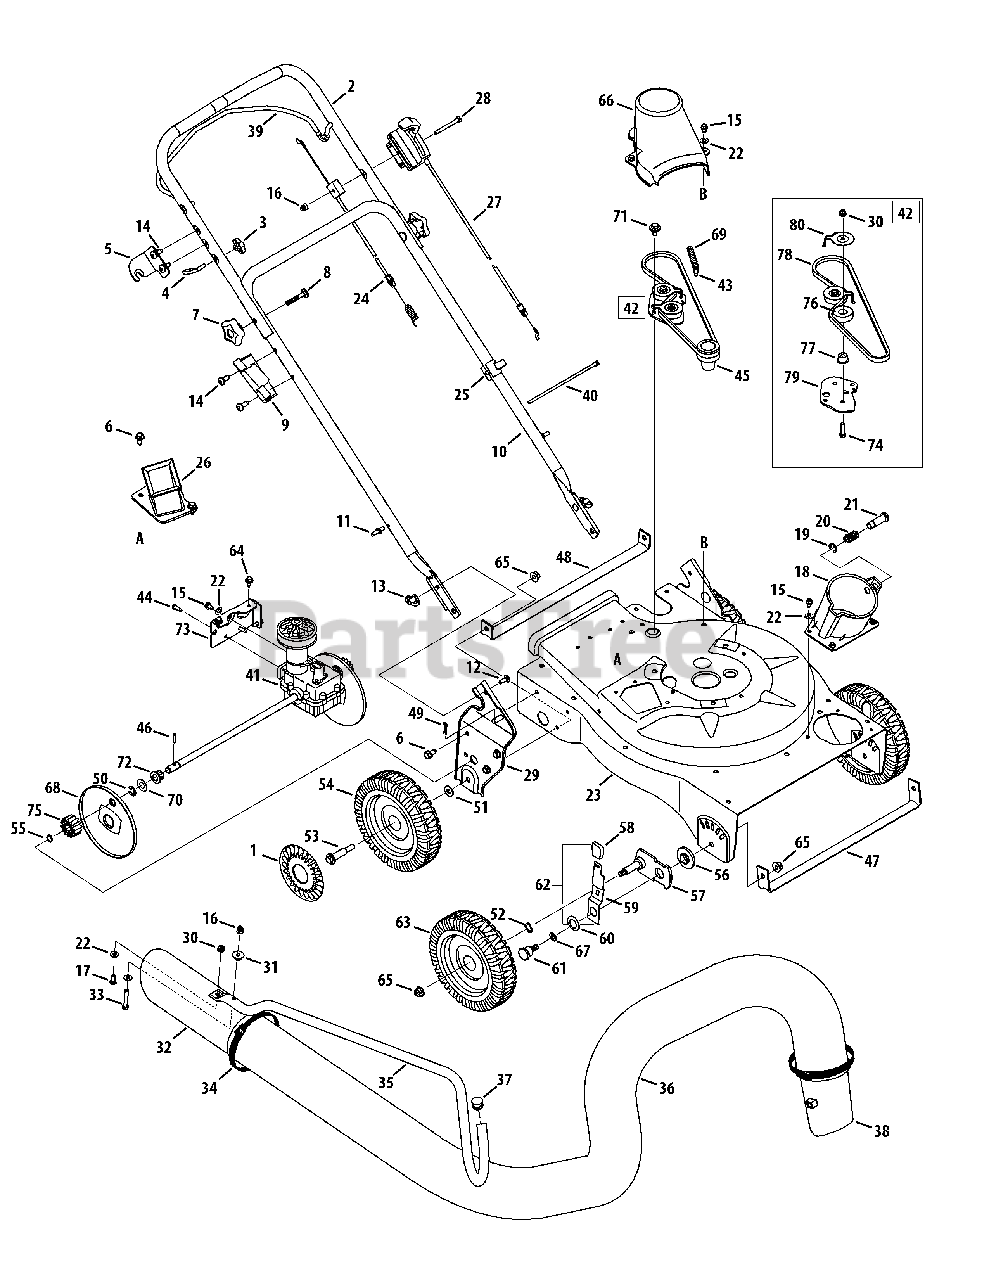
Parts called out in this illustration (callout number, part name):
1	Hub Cap
2	Upper Handle
4	Eye Bolt
5	Upper Handle Bracket
6	Hex Cap Screw 5/16-12 x.750
7	Handle Knob 5/16-18
8	Carriage Bolt
9	Nozzle Handle Clip
10	Lower Handle
11	Studs
12	Carriage Screw 1/4-20 x.75
13	Wing Nut 1/4-20
14	TT Screw, 5/16-18 x .750
15	Screw, 1/4-20 x .500
16	Cap Lock Nut, 1/4-20
17	Hex Cap Screw 1/4-20 x.620
18	Hose Base Adapter Assembly (Incl. Ref.# 19-21)
19	E Ring.500 Dia
20	Compression Spring
21	Clevis Pin
22	Flat Washer.271 ID x.630 OD
23	Upper Flail Housing
24	Drive Control Cable
25	Cable Guide
26	Chipper Chute Assembly
27	Speed Control Cable
28	Hex Screw, 1/4-20 x 2.50
29	Handle Bracket Ass’y RH
30	Flange Lock Nut, 1/4-20
31	Spacer
32	Hose Nozzle
33	Hex Cap Screw 1/4-20 x 2.625
34	Adjustment Clamp
36	Vacuum Hose
37	Handle Plug
38	Hose Adapter
39	Drive Control
40	Cable Tie
41	Transmission Assembly
42	Idler Assembly (Incl. Ref.# 74-80)
43	Shoulder Screw, #12-24 x .30 x .46
44	Screw, #12-16 x .750
45	Impeller Hub
46	Dowel Pin
47	Front Wheel Support Brace
48	Rear Wheel Support Brace
49	Cotter Pin
50	E-Ring
51	Flat Washer, .406 x .875 x .105
52	Wave Washer.531 ID x.781 OD
53	Shoulder Screw 3/8-16
54	Rear Wheel
55	Snap Ring
56	Height Adjustment Bearing
57	Pivot Arm Assembly
58	Height Adjustment Knob
59	Spring Lever
60	Bell Washer.760 ID x.25 OD
61	Shoulder Screw,.750 x.500
62	Height Lever Assembly (Incl. Ref.# 58-59)
63	Front Wheel
64	Screw, 1/4-20 x .625
65	Flange Lock Nut, 3/8-16
66	Belt Cover
67	Thrust Washer.375 ID x.70 OD
68	Wheel Cover
69	Extension Spring,.375 x 2.95
70	Flat Washer,.508ID x1.00OD x.020
71	Shoulder Screw,.560 x.165
72	Drive Axle Bushing
73	Transmission Mounting Bracket
74	Screw, 1/4-20 x 1.00
75	Spur Gear - RH
76	Ball Bearing
77	Flange Spacer,.260 x.659 x.517
78	Belt, 3/8 x 32.5
79	Idler Bracket
80	Belt Keeper
